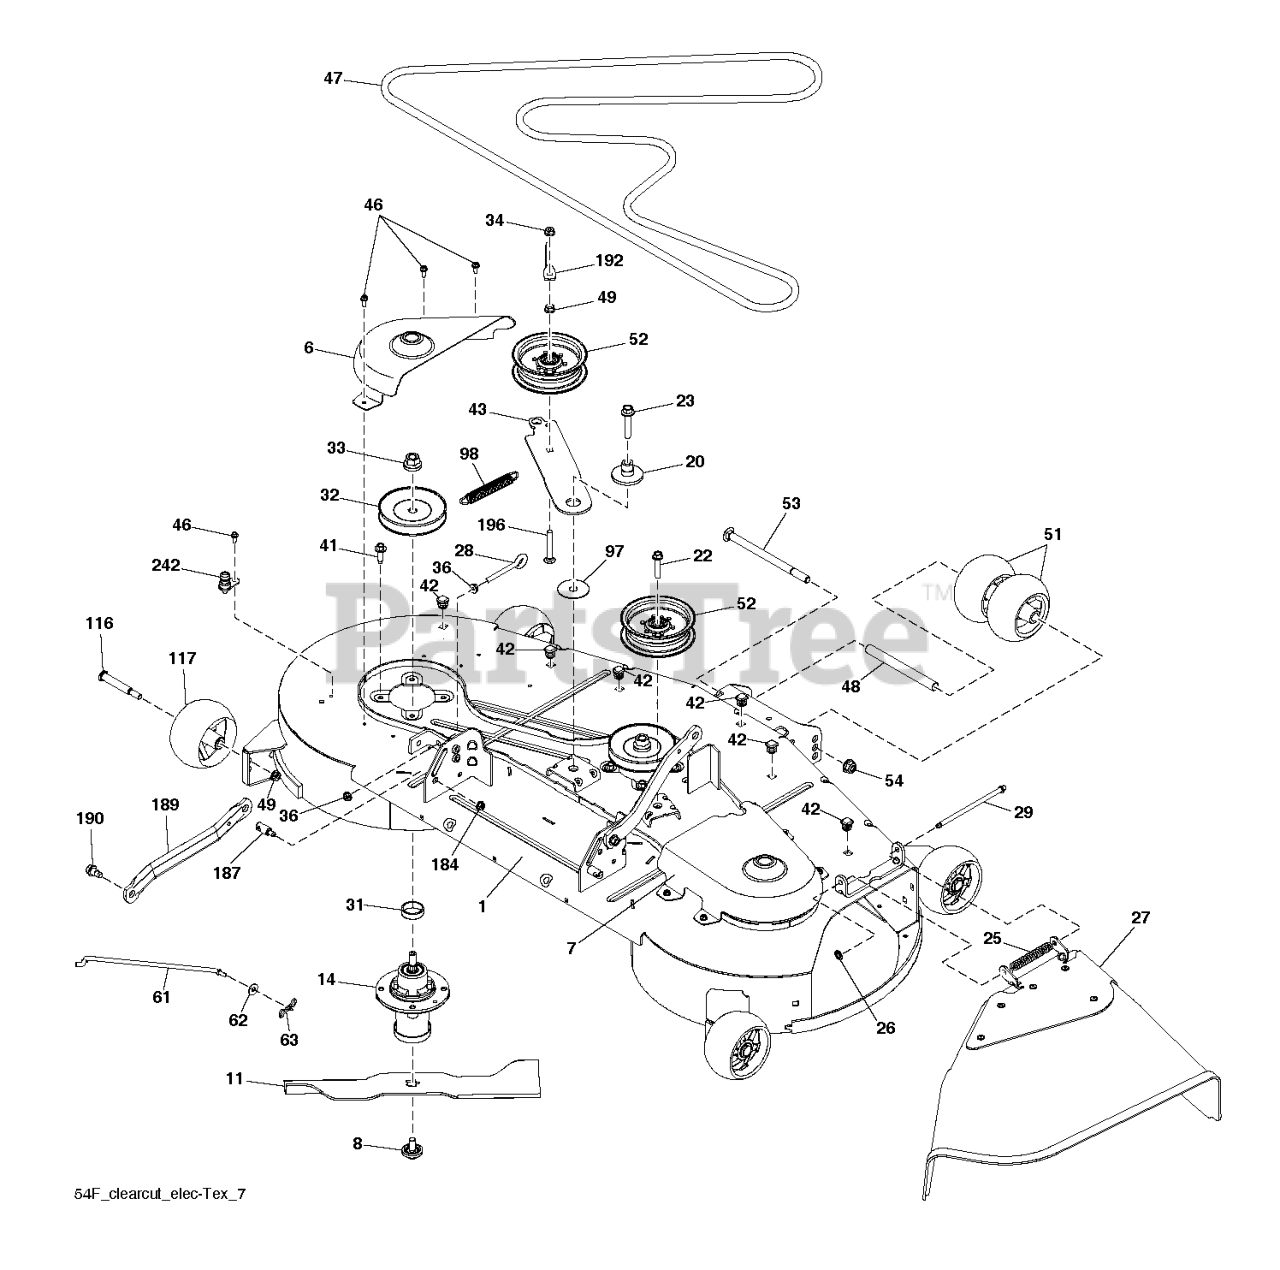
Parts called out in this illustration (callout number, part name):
1	DECK.SVC.WLDT.54CC.428
6	COVER 54 CLEARCUT, LH MANDREL,
7	COVER 54 CLEARCUT RH MANDREL B
8	BOLT.WASHER.ASM.7/16-2
11	BLADE CC54 PZ STYLE HI LIFT BL
14	MANDREL ASM, CAST IRON
20	SPACER.IDLER.PULLY.HUB
22	SCREW LT
23	SCREW.7/16-14 X 2.125.WASHER
25	SPRING.42.FCS.DEFLECTOR
26	NUT PUSH M
27	DEFLECTOR ASSY 54 CLEARCUT RES
28	EYE BOLT 5/16 X 3.50
29	FLAT IDLER PULLEY
31	WASHER.SPACER.MANDREL
32	PULLEY/MANDREL
33	NUT.FLANGE.LOCK.TOP
34	LOCKNUT
36	NUT 5/16C WHIZ
41	BOLT.HEX.WASHR.HED.313-18X1.19
43	ARM IDLER ARM, CLEARCUT 54 BLA
46	SCREW.1/4-20X5/8
47	BELT CLEARCUT 54, TRACTOR DECK
48	TUBE, ROLLER AXLE LONG
49	NUT LOCK FLG 3/8-16 UNC
51	ROLLER, GAUGE .635 BORN
52	PULLEY.IDLER.2006
54	NUT, 1/2-13 HEX FLG NYLOC ZD
61	ROD.ANTI.SWAY.48/54"TE
62	WASHER
63	PIN.COTTER.5/16.BOW TI
98	SPRING.EXTN.42.FCS.TR.DECK.DRV
116	BOLT.SHOULDER.3/8-16X3-5/8.
117	WHEEL.GAUGE.RALLY
184	NUT LOCK HEX FLANGE 5/16-18
187	STUD.FASTNER.W/ANTI-ROTATE
189	ARM.RFIXED.MOWER.SUSPNSIONX431
190	BOLT.SHOULDER
192	KEEPER.BELT.IDLER.54"T
196	CARRIAGE BOLT 3/8-16 X
242	PORT.WASHOUT
